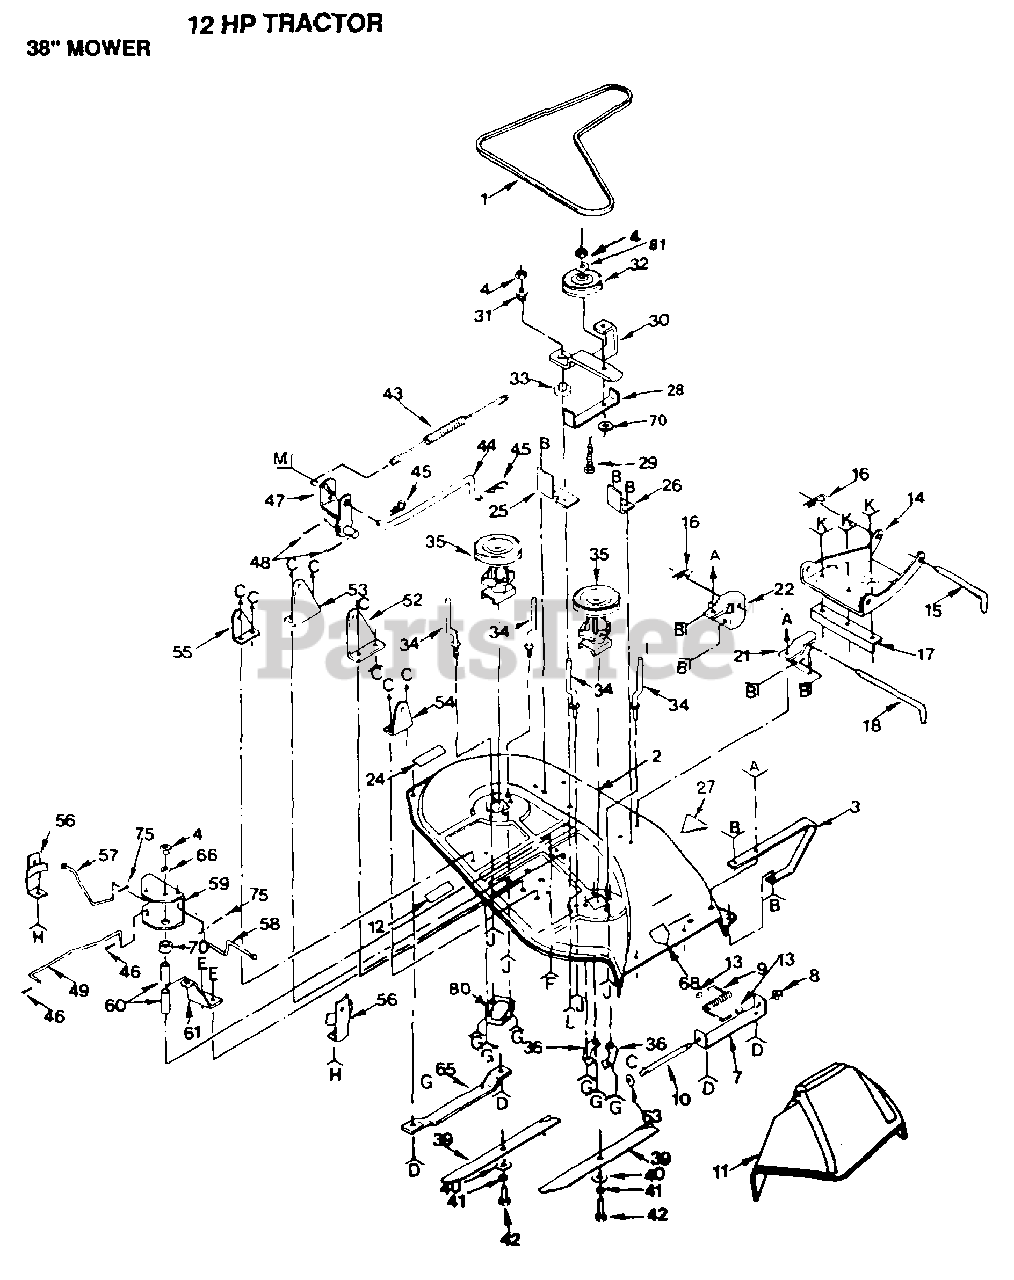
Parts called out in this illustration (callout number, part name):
8	NUT PUSH M
10	ROD-HINGE T
11	DEFLECTOR-SHLD T
12	DECAL.LT
13	CAP-SLEEVE LT
14	LINK.PARALLEL
15	"ROD, FRT. PARAL T"
16	SPRING.RETAINER
17	LINK STOP
18	HINGE PIN T
21	BRACKET RH LT
22	BRACKET LH T
24	DECAL YT
25	SUPPORT ARM T
26	STOP T
31	SPACER RETAINER
32	PULLEY IDLER
33	"WASHER, WEAR LT"
34	BELT KEEPER LT
35	"JACKSHAFT.38""LT"
36	SUPPORT PLATE LT
39	"BLADE.38"" HI-LI"
40	WASHER
42	BOLT.3/8-24X1-1/2
45	SPRING.RETAINER
47	ROCKSHAFT T
49	ROD BRAKE LT
54	"BRKT,SUSP RH T"
55	"BRKT,SUSP REAR LH"
56	BRAKE LT
57	"ROD, BRAKE LH LT"
58	ROD BRAKE LT
59	"BRK,BRAKE,PVT LT"
60	SPACER BRAKE LTV
61	BRACKET SUPT LTV
65	RUNNER-LH M
66	WASHER
68	DECAL WARNING
80	SUPPORT T
81	WASHER
